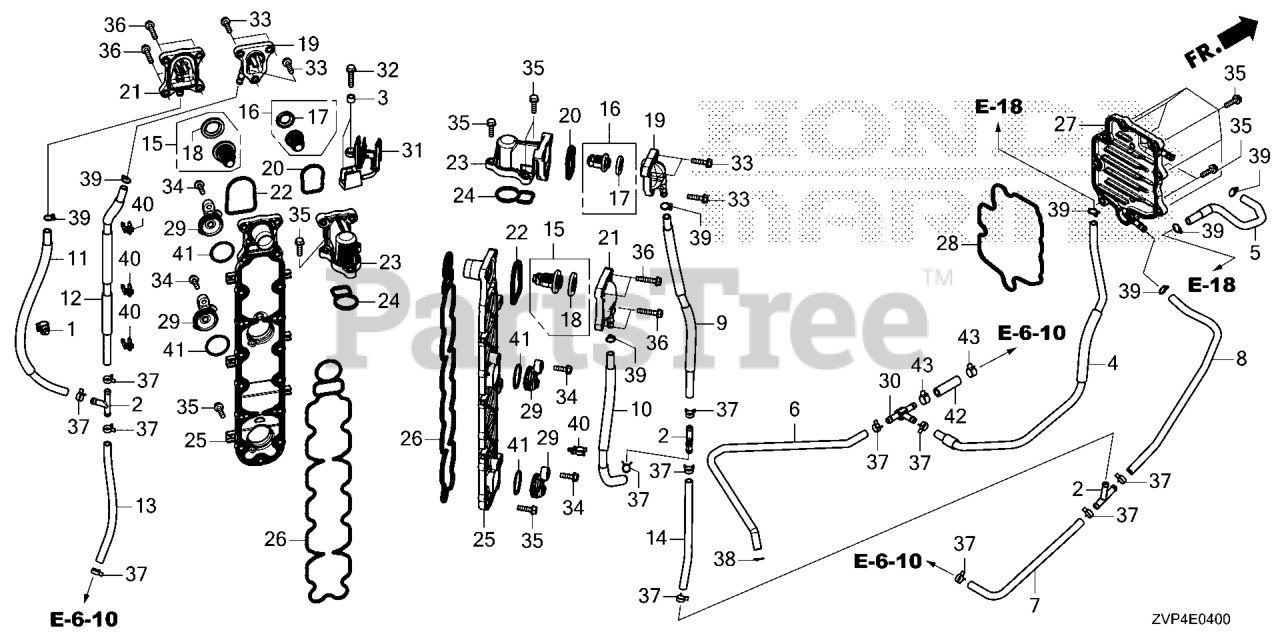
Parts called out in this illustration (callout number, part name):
1	CLAMP B, FUEL TUBE
2	JOINT, FUEL TUBE
3	COLLAR, DISTANCE (6.5X11X7.5)
4	TUBE A, WATER INLET
5	TUBE COMP C
6	TUBE, WATER CHECK
7	TUBE A, WATER OUTLET
8	TUBE B, WATER OUTLET
9	TUBE COMP (7X320)
10	TUBE COMP (7X320)
11	TUBE COMP (7X340)
12	TUBE COMP (7X360)
13	TUBE WATER (7X195)
14	TUBE WATER (7X215)
15	THERMOSTAT ASSY.
16	THERMOSTAT ASSY.
17	RUBBER, RING
18	RUBBER, RING
19	COVER, THERMOSTAT A
21	COVER, THERMOSTAT B
23	CASE, THERMOSTAT
24	PKG, THERMOSTAT CASE
25	COVER, W/J
26	PKG, W/J COVER
27	COVER W/J F
28	PKG, W/J COVER F
29	COVER, ANODE
30	JOINT, THREE WAY
31	HOLDER, CONNECTOR
32	BOLT, FLANGE (6X30)
33	BOLT, FLANGE (6X25)
34	BOLT, FLANGE (6X20)
35	BOLT, FLANGE (6X22)
36	BOLT, FLANGE (6X32)
37	CLAMP, TUBE (D10.5) (ENGINE NO.)
38	CLIP, TUBE (B1 11)
39	CLIP, TUBE (B12)
40	CLAMP, HOSE (NOT AVAILABLE)
41	O-RING (33X2.4)
43	CLAMP D12.5, TUBE
